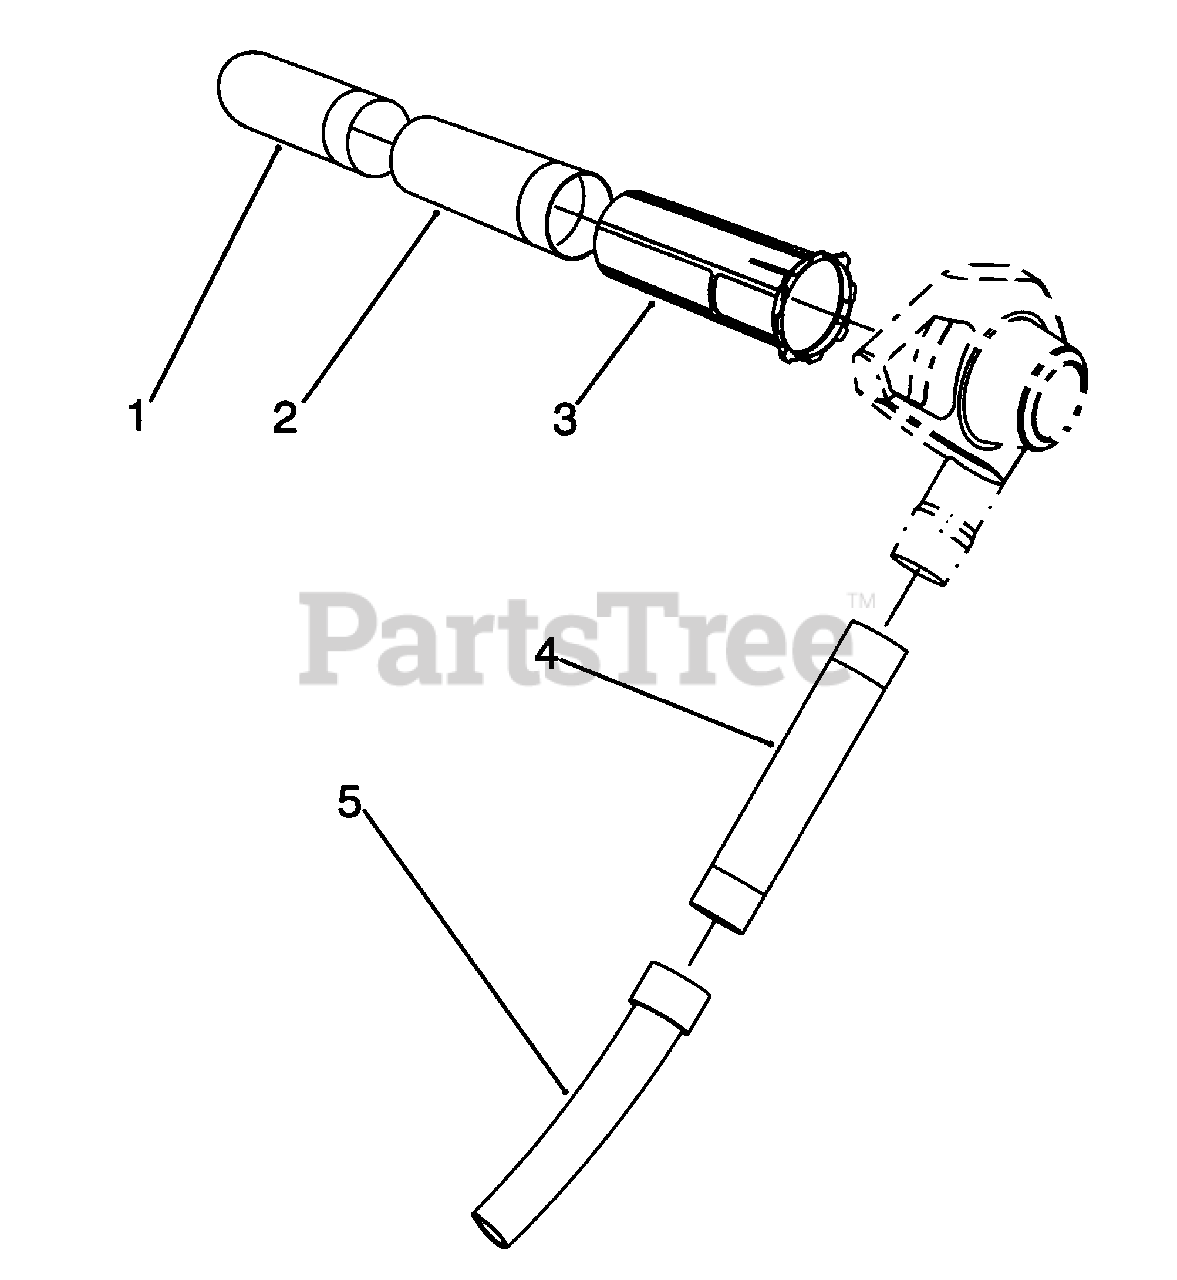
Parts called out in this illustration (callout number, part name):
1	Vac Tube-Lower
2	Vac Tube-Middle
3	Vac Tube-Upper
4	Tube-Blower
